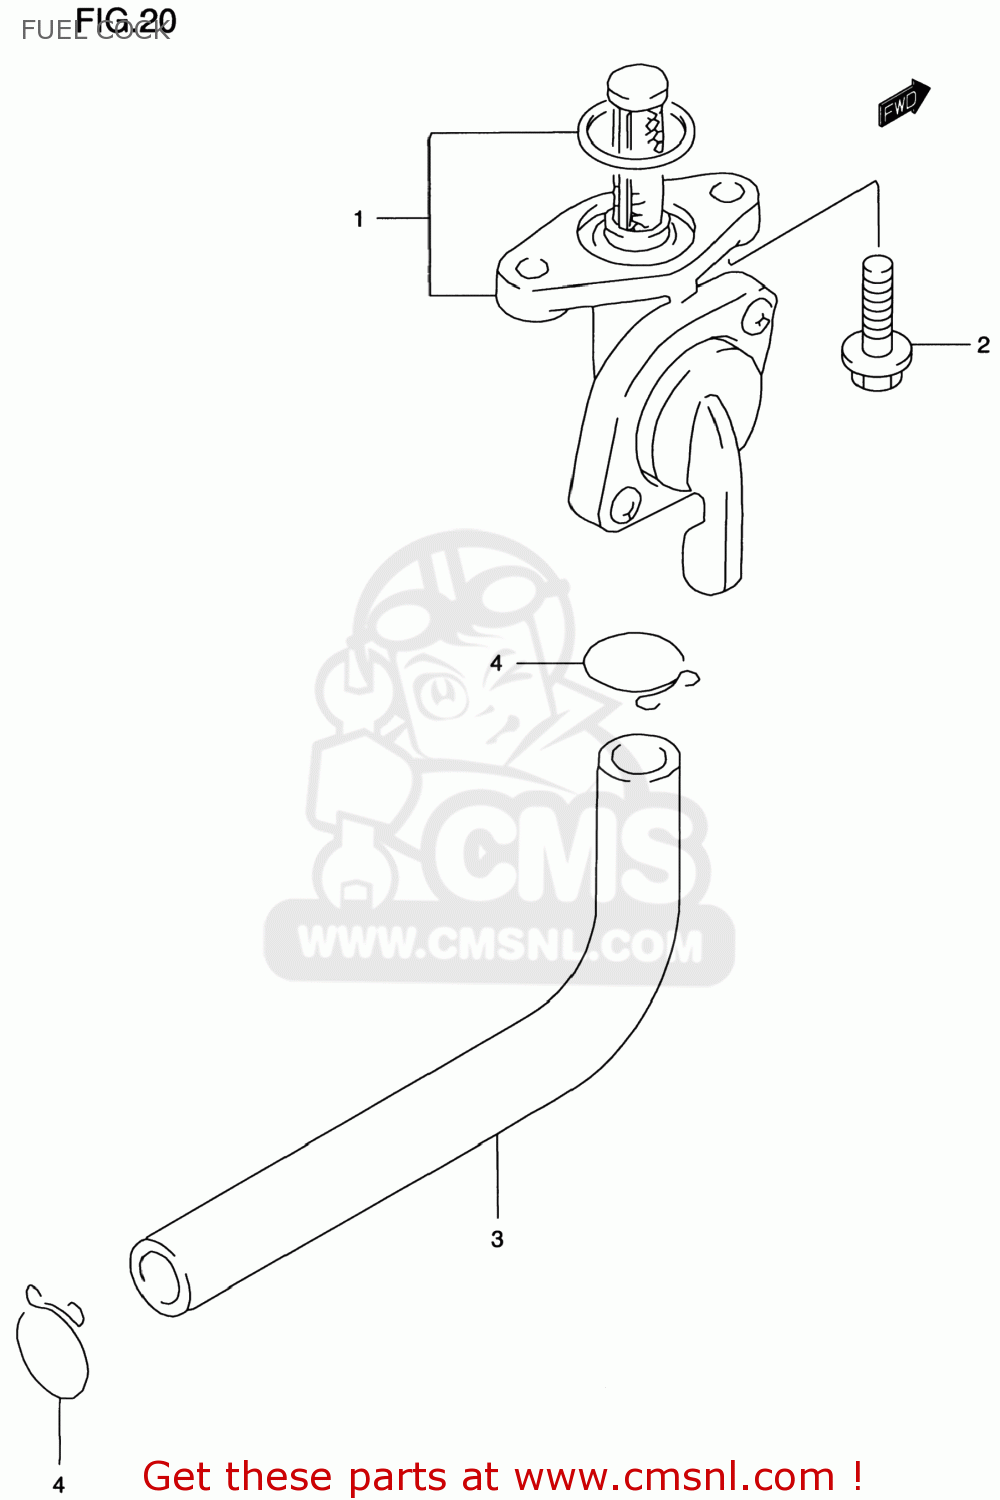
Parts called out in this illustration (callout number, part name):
1	COCK ASSY,FUEL
2	BOLT
3	HOSE,FUEL
4	CLIP
